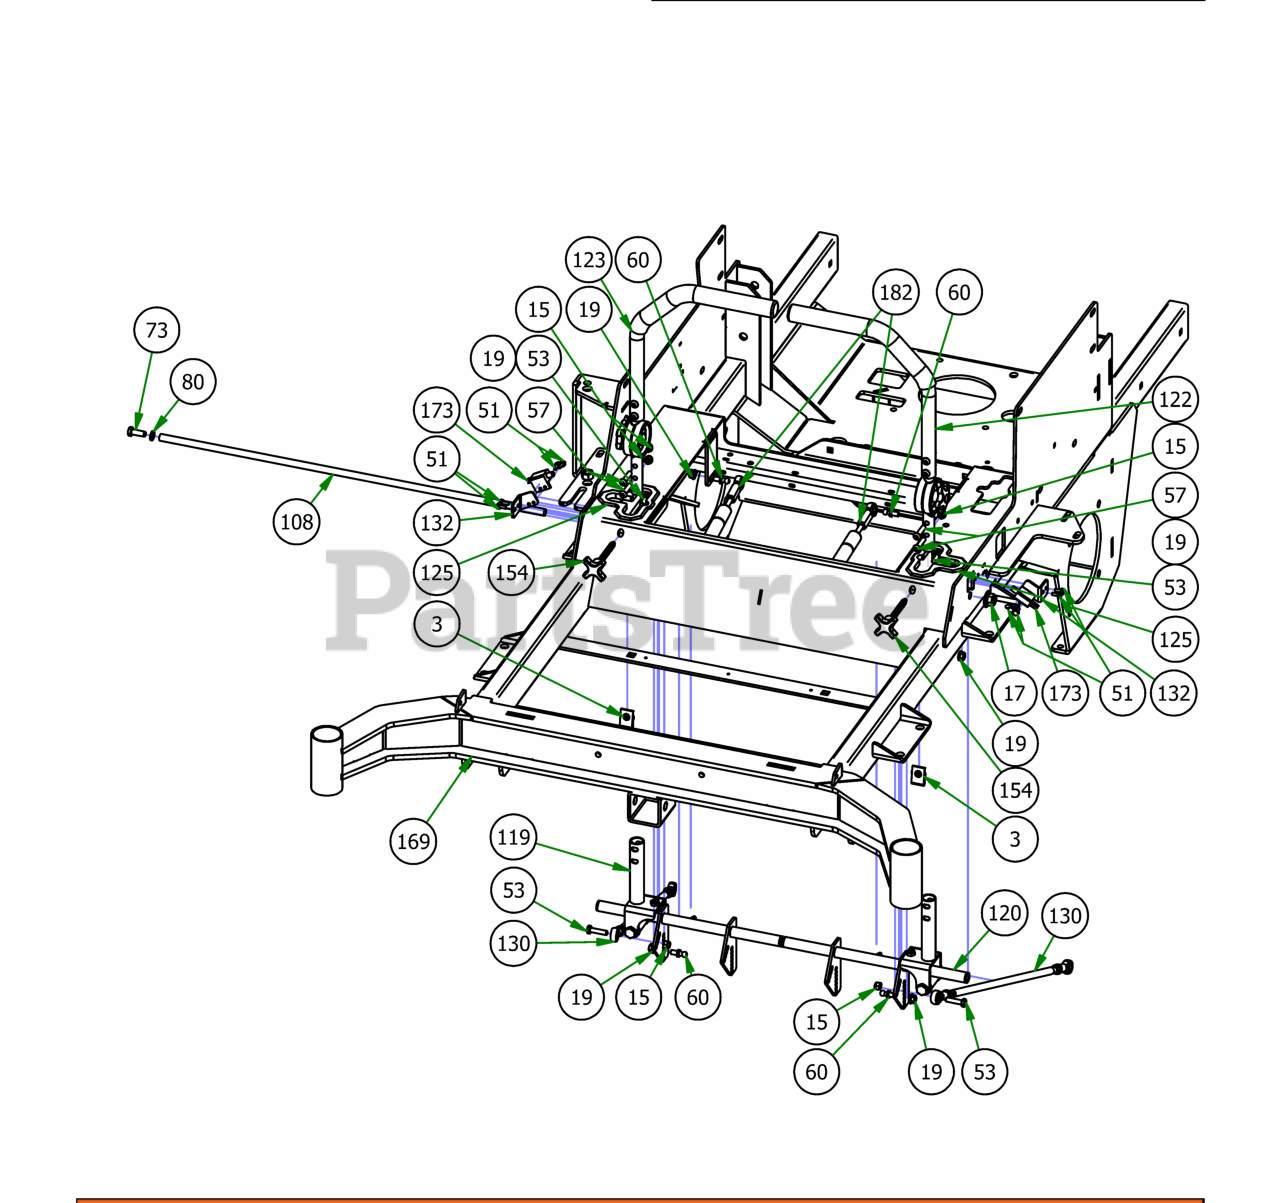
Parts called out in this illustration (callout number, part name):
3	Extruded Nut 3/8"-16 3/4" Hole Center With Patch
15	5/16-18 Nylock Insert Locknut
17	1/2-13 NYLON INSERT FLANGE LOCKNUT ZINC
19	5/16" Flange Nut
51	12-24x 1/2 HWH Bolt
53	5/16 x 1 1/4 Hex Bolt
57	5/16-18 UNC X 1-3/8" BHCS, TORX DRIVE, GR 5
60	10mm Damper Ball Stud-Steering
73	3/8" x 1" Hex Bolt
80	3/8" Lock Washer
108	2019 Steering Actuator Rod
119	2019 R Series RH Arm Rod Assembly
120	2019 R Series LH Arm Rod Assembly
122	2019 Left Hand ADJ. Steering Arm Kit
123	2019 Right Hand ADJ. Steering Arm Kit
125	Snap-In Bushing-2019
130	2019 Rebel Push Rod Assembly
132	2019 Arm Switch Bracket
154	Speed Limiting Knob 3/8-16X 3"
169	2019 Rebel Frame - Powdercoated
173	Safety Switch
182	Steering Damper
